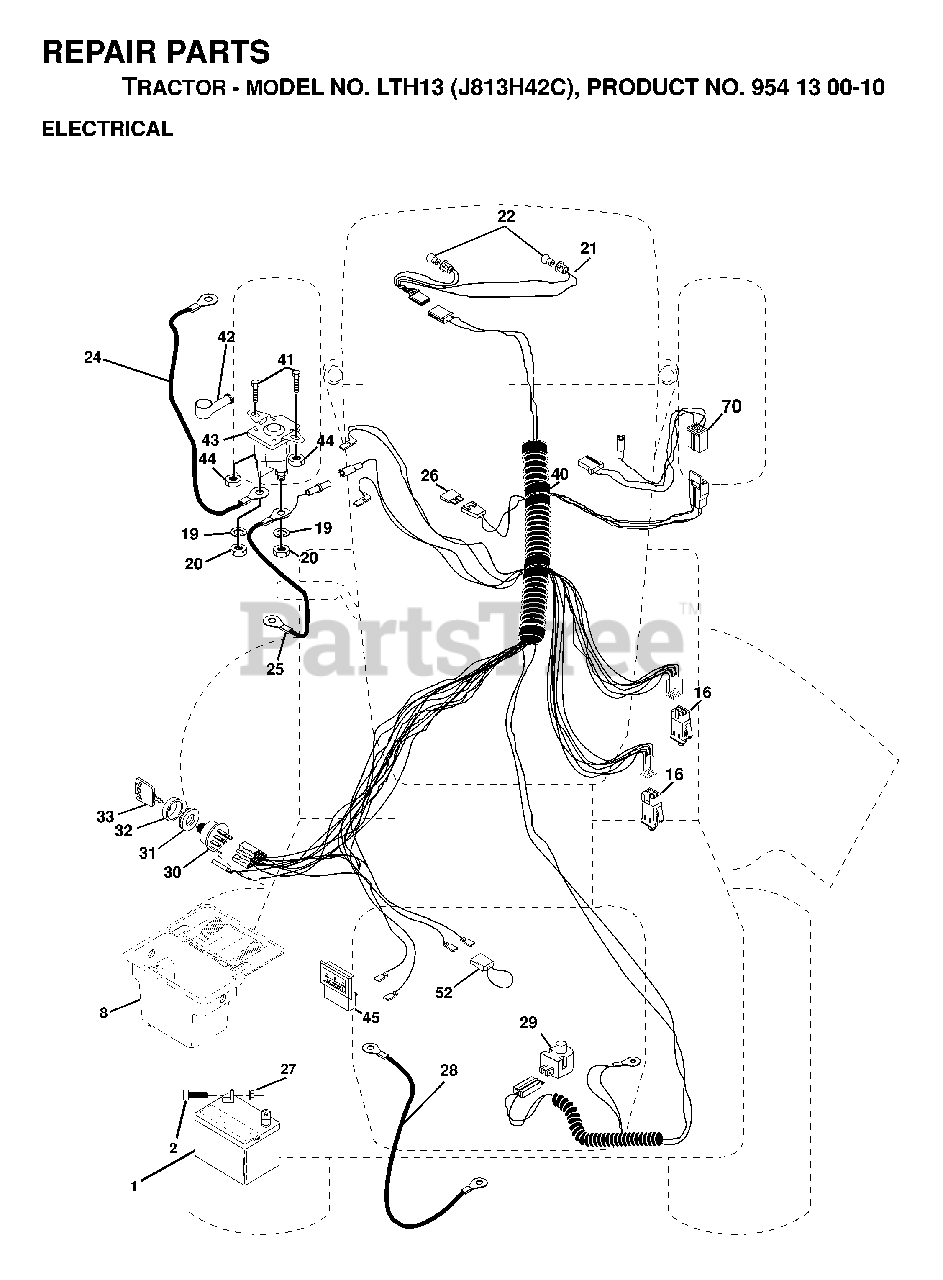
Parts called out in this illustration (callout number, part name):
1	BATTERY 12 VOLT 25 AMP
8	CASE BATTERY MECH HINGE
16	SWITCH INTERLOCK
19	LOCKWASHER
20	NUT
21	HARNESS ASM HDLIG
22	LIGHTBULB
24	BATTERY CABLE GT
25	CABLE BATTERY
27	NUT
28	CABLE T
29	SWITCH SEAT
30	SWITCH.IGNITION.4.POSITION
31	NUT IGNITION
32	COVER SWITCH KEY
40	HARNESS IGN
42	TERMINAL COVER
43	SOLINOID
52	WIRE PROTECTION LOOP
70	HARNESS, ENGINE
